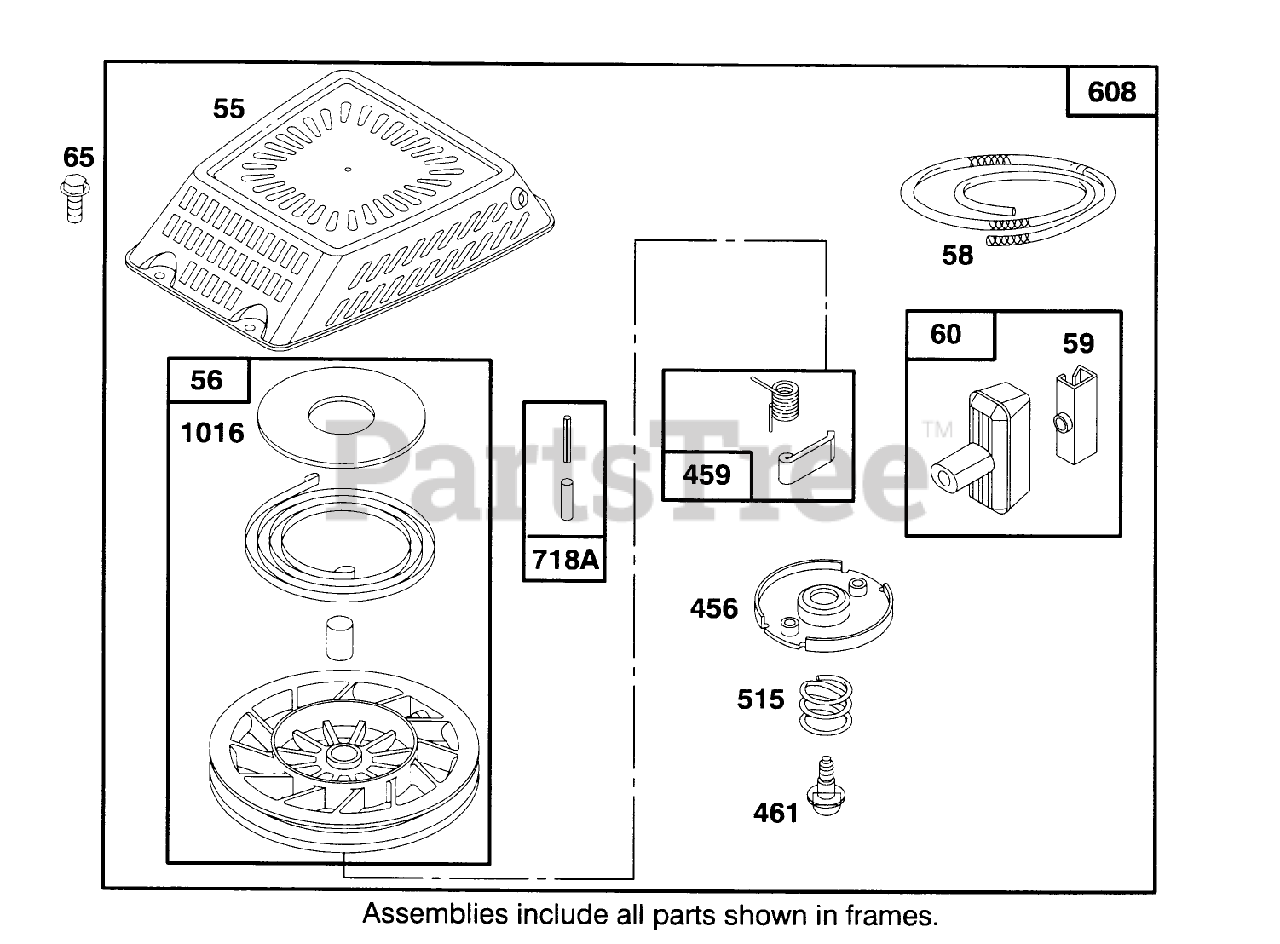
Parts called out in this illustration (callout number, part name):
60	HANDLE-REWIND STARTER
456	RETAINER - SPRING
515	SPRING - RETAINER
